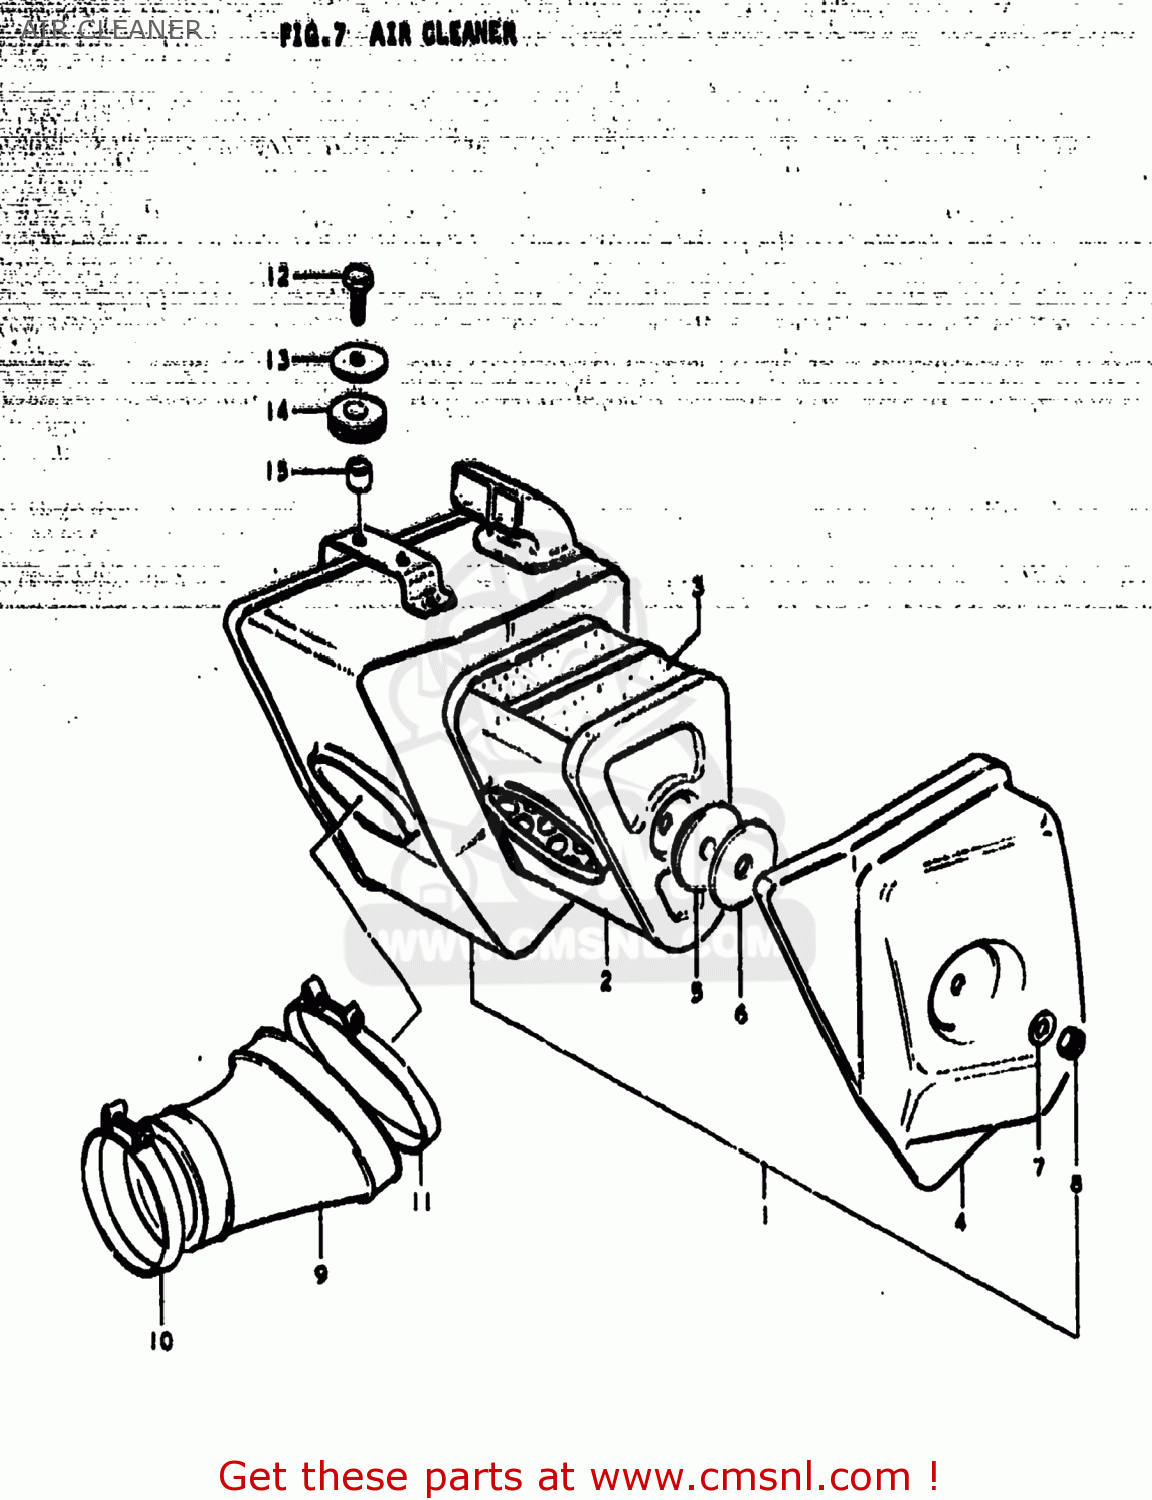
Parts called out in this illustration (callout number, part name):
1	CLEANER ASSEMBLY,AIR
2	FILTER ASSY,AIR CLEANER
3	FILTER
4	CAP
5	SEAL
6	SPACER
7	WASHER
8	NUT
9	HOSE,CARBURETOR AIR INLET
10	CLAMP
11	CLAMP
12	BOLT, UPPER
13	WASHER (6.5X20X1.2)
14	CUSHION
15	SPACER (7X9X7)
